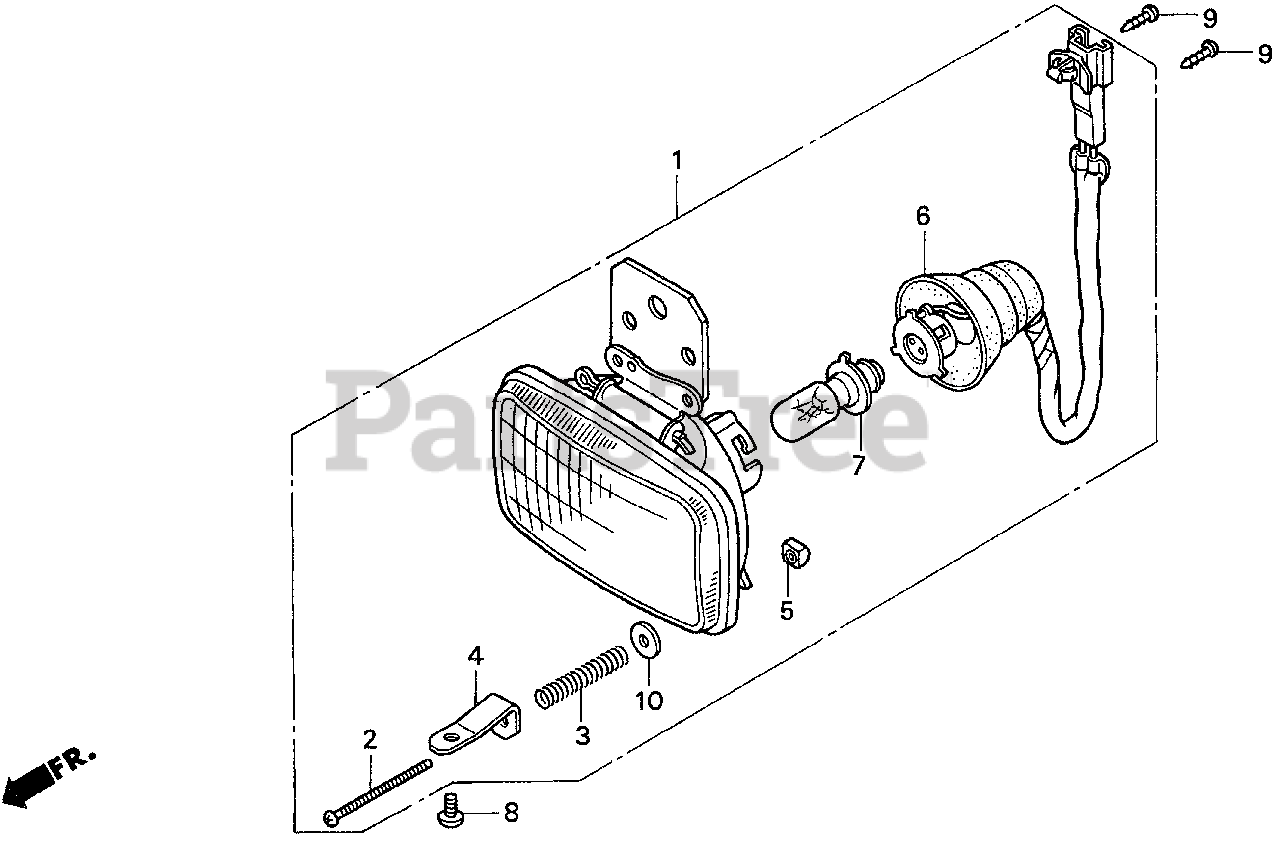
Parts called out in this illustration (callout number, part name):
1	HEADLIGHT ASSY.
2	SCREW, BEAM ADJUST
3	SPRING, HEADLIGHT BEAM ADJUSTING
4	STAY, HEADLIGHT
5	NUT, BEAM ADJ. (STANLEY)
6	SOCKET ASSY., HEADLIGHT
7	BULB (12V25/25W) (STANLEY)
8	SCREW, VISOR SETTING
9	SCREW, TAPPING (5X12)
10	WASHER, PLAIN (3MM)
